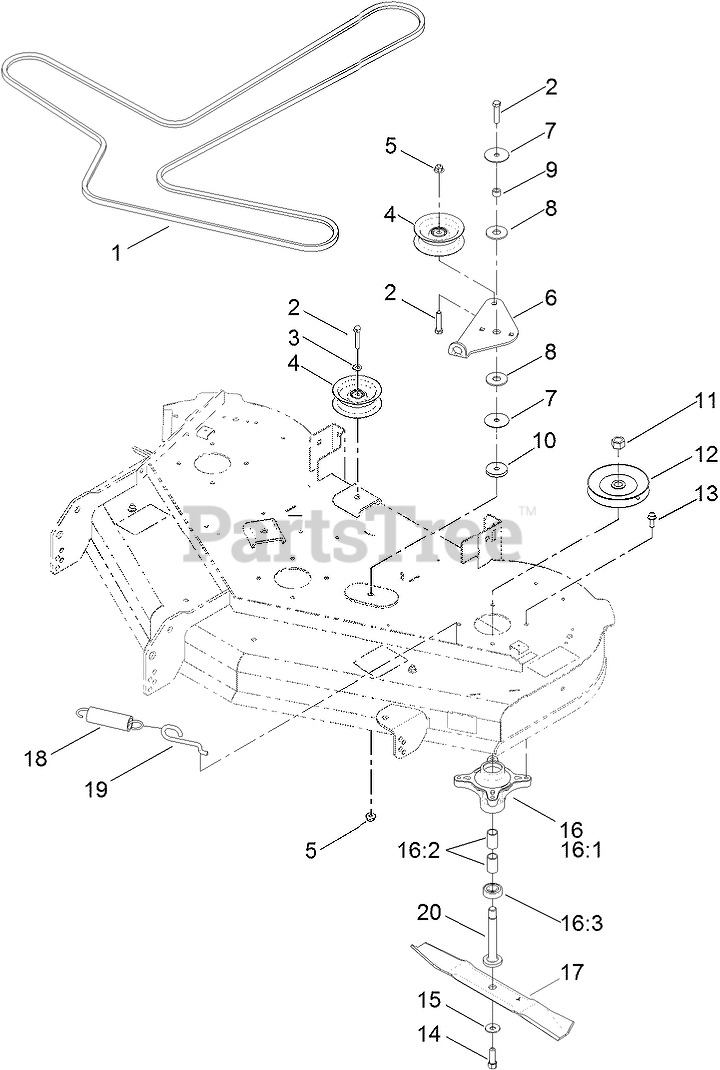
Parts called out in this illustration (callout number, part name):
1	V-BELT
2	SCREW-HH
3	WASHER-FLAT
4	PULLEY-IDLER, FLAT
5	NUT-HF, NI
6	ARM-IDLER
7	WASHER
8	WASHER-FRICTION, COMPOSITE
9	SPACER
10	WASHER-PLAIN
11	NUT-HEX
12	PULLEY
13	SCREW-TAPTITE
14	SCREW-HH
15	WASHER-BELLEVILLE
16	SPINDLE ASM
16:1	SPINDLE
16:2	SPACER
16:3	BEARING-BALL
17	BLADE-MULCH, 17.50 INCH
18	SPRING-EXTENSION
19	HOOK-RETURN, SPRING
20	SHAFT-SPINDLE
